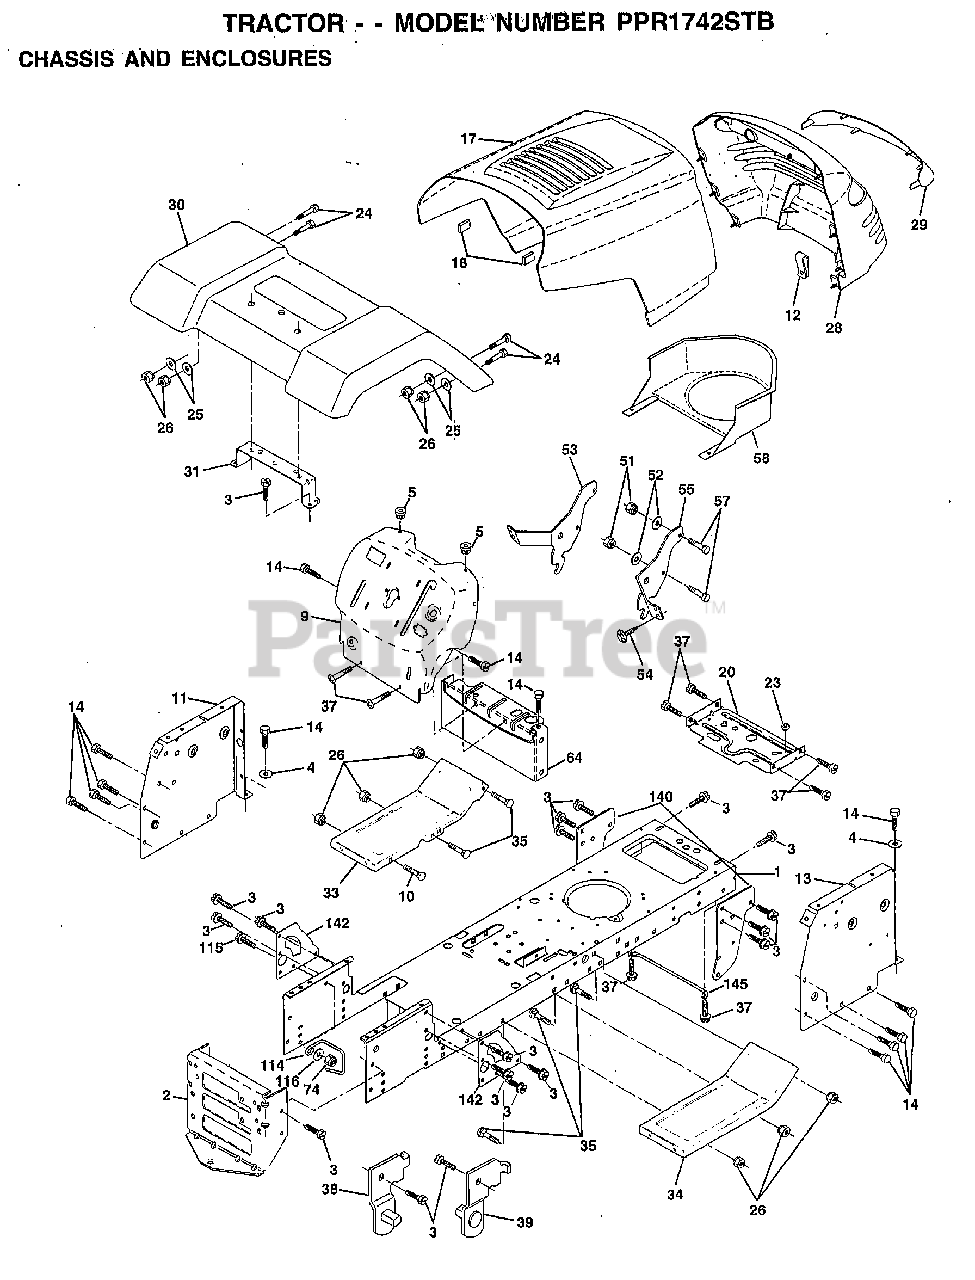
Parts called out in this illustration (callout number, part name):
1	CHASSIS.STLT.STAMPING
3	SCREW
4	WASHER
5	BUMPER-HOOD/DASH
11	"PANEL-DASH,LH"
12	CLIP.TINNERMAN
13	PANEL.ASM.DASH.RH
14	SCREW LT
17	"HOOD W/TRIM,MS428"
20	"PLATE-MTG,BATT/FU"
24	BOLT
25	WASHER
26	NUT
28	GRILL
29	GRILLE.LENS
30	FENDER.FOOTREST.SPLT.PNT
31	BRACKET SUPT FEND
33	FOOTREST PNT LH
34	FOOTREST.RH.LT/GT
35	BOLT
37	SCREW LT
38	BRACKET ASM LH
39	BRACKET ASM RH
51	NUT
52	WASHER
53	BRACKET.GRILLE.LH
54	SCREW.HEX.WS.HD
55	BRACKET.GRILLE.RH
58	AIR DUCT
64	DASH-LOWER
114	"KEEPER-BELT,RR.LH"
115	SCREW
116	WASHER
140	BRKT SUSPENSION
142	PLATE.REINFORCEMENT
145	"ROD POVOT,CHASSIS"
